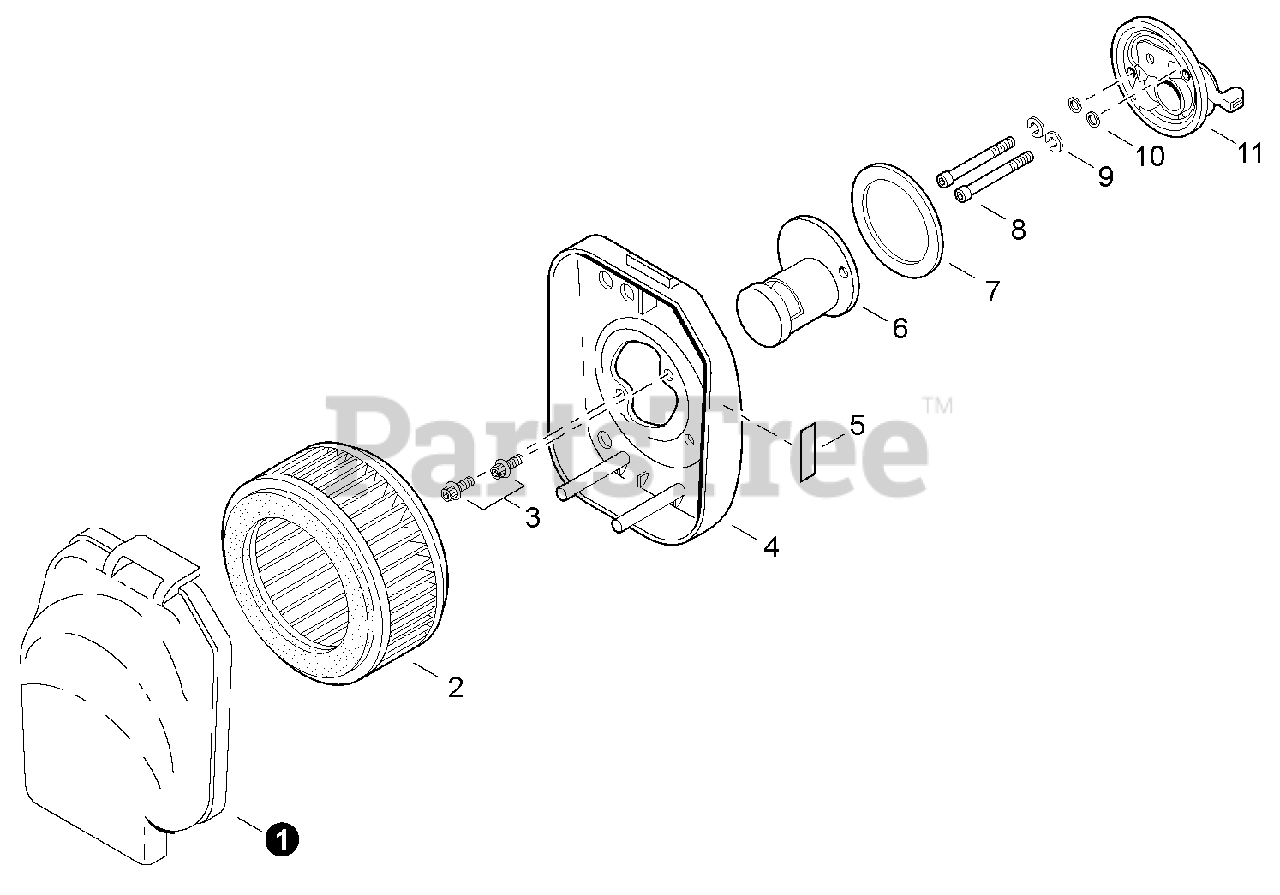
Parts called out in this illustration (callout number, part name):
1	COVER, AIR FILTER
2	FILTER, AIR
3	BOLT M4×14
4	CASE, AIR FILTER
5	LABEL, CHOKE
6	PIPE, INTAKE
7	GASKET, INTAKE
8	BOLT 5×60
9	WASHER, SPRING 5
10	WASHER, FLAT 5.5×10×0.8
11	CHOKE ASSY
